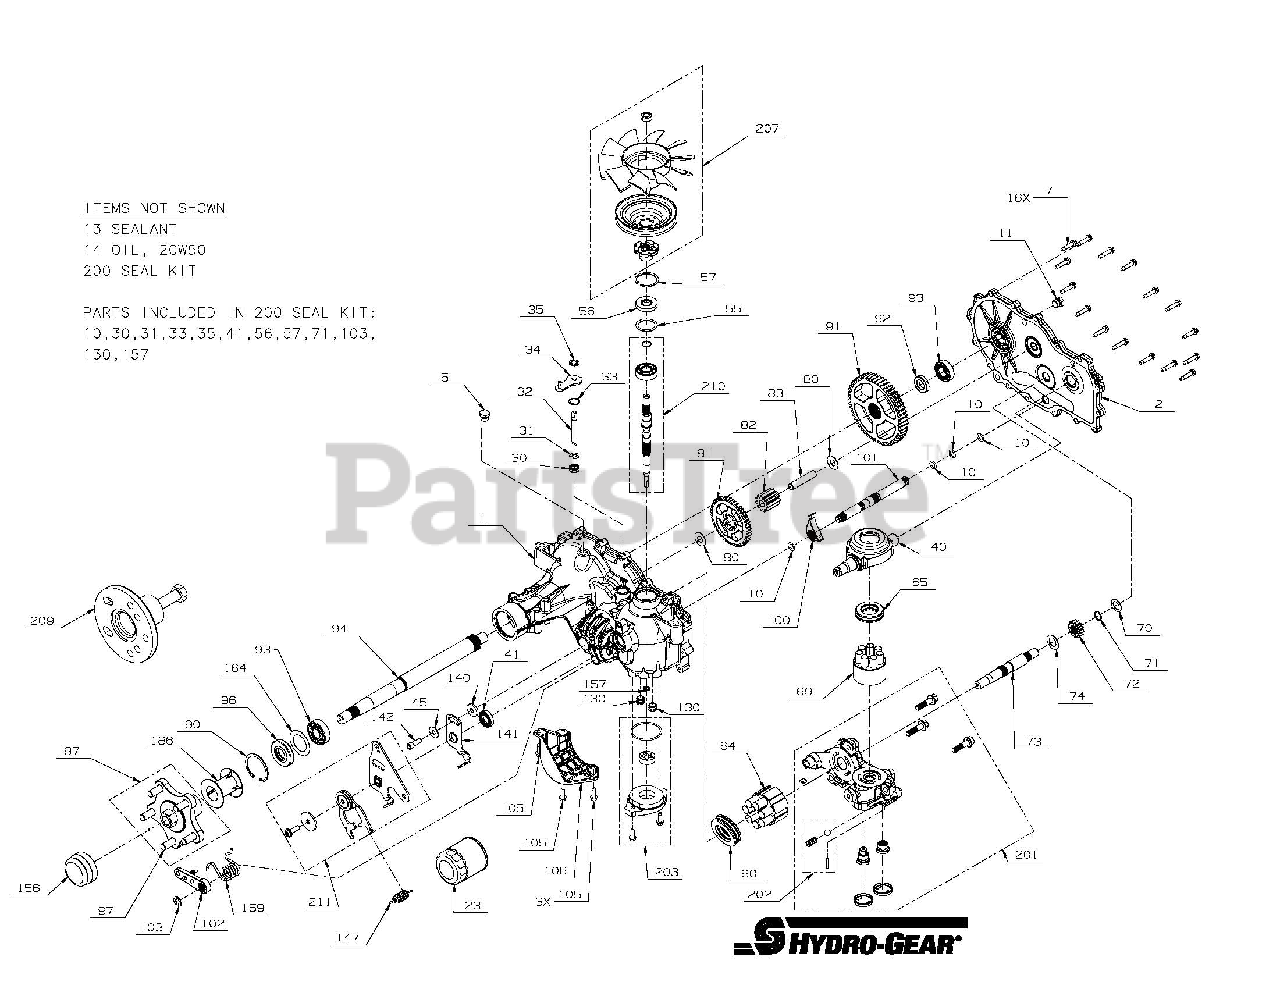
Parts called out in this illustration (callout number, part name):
7	SCREW, HEX WASHER
13	TUBE, SEALANT
23	FILTER, SPIN-ON 2.6 X 3.0
30	SEAL, LIP .375 X .75 X .25
31	RING, RETAINING EXTERNAL .375
33	RING, RETAINING .750, INTERNAL
34	ARM, BYPASS
35	RING, RETAINING .375 EXTERNAL
40	SWASHPLATE, TRUNNION
41	SEAL, LIP 18 X 32 X 7
45	WASHER FLA-1.34 X .88 X .06
55	WASHER, FLAT 1.23 X 1.57 X .04
56	SEAL, LIP 17 x 40 x 7
57	RING RETAINING INTERNAL
60	BEARING, THRUST 35 x 62 x 18
64	KIT, 16cc CYLINDER BLOCK ASSEMBLY
65	BEARING, THRUST 30 x 52 x 13
69	KIT, BLOCK 7 PISTON
70	WASHER, .63 X 1.00 X .05 FLAT
71	RETAINING RING, MOTOR SHAFT
74	WASHER, .71 X 1.16 X .04 FLAT
80	WASHER, .51 X 1.00 X .03 FLAT
83	PIN, JACKSHAFT
90	RING, RETAINING 2.25 INTERNAL
96	SEAL, LIP, TC4, 1.0 X 2.06 X .38
97	KIT, HUB - 5 BOLT
102	KIT, RIGHT HAND BRAKE ARM
105	SCREW, HEX WASHER 1/4-20 X .75
106	GUARD, FILTER, RH
140	SPACER 0.320 ID X 1.005 OD X 0.1495 -THK
141	ARM, NEUTRAL RIGHT
142	SHCS 5/16-24 x 7/8
147	SPRING, EXTENSION
159	SPRING, TORSION
200	KIT, SEAL, ZT-2800
203	KIT, CHARGE
207	KIT, FAN/PULLEY
209	KIT, HUB PULLER
210	KIT, INPUT SHAFT
211	KIT, RTN CW
